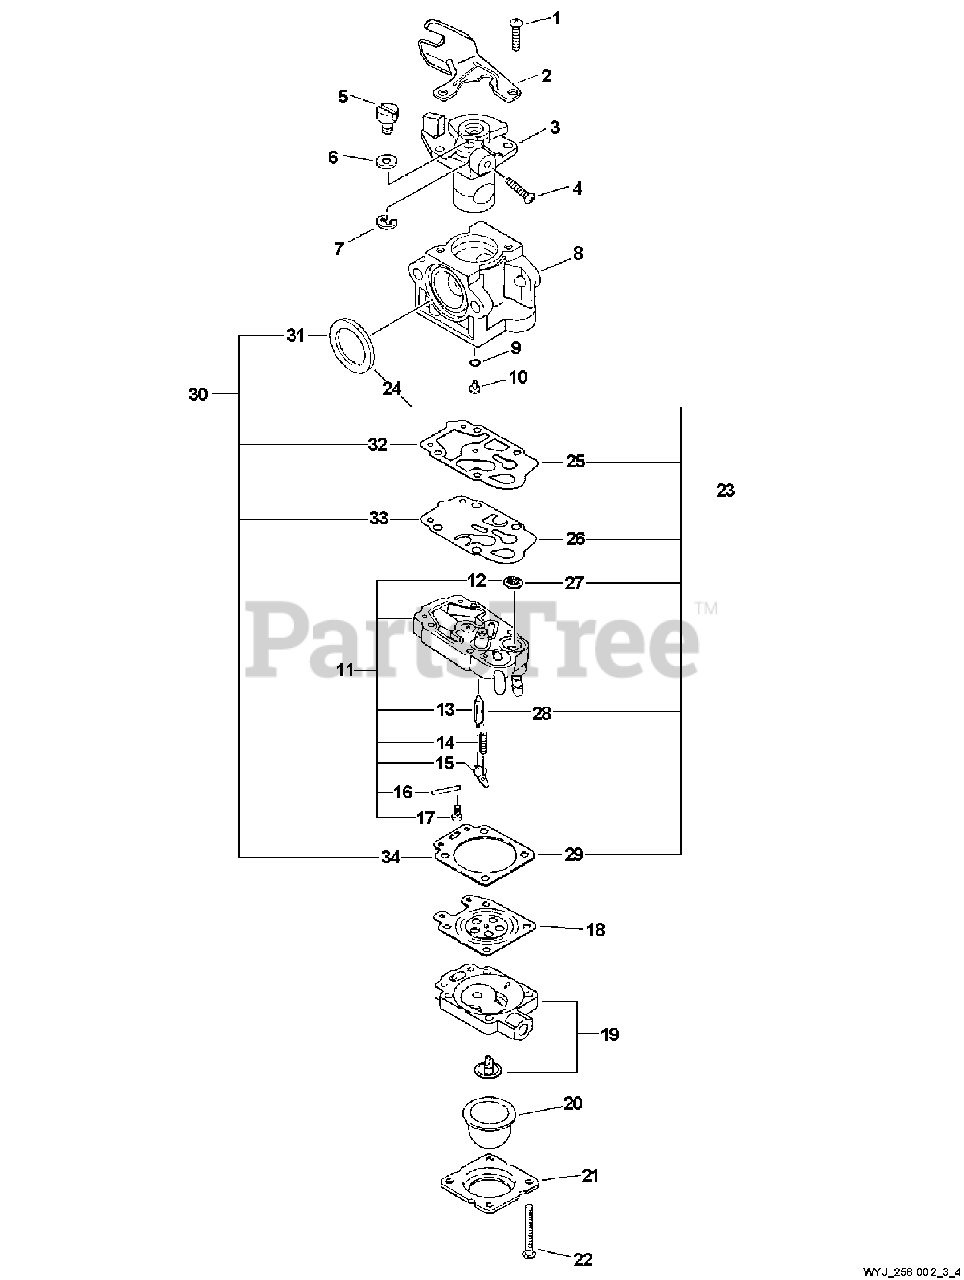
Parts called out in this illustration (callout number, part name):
2	BRACKET, CABLE
3	THROTTLE VALVE ASSY
4	SCREW, IDLE ADJUST
7	RING, RETAINING
8	BODY, CARBURETOR
11	PUMP BODY ASSY
12	STRAINER
13	VALVE, INLET NEEDLE
14	SPRING, METERING LEVER
15	LEVER, METERING
16	PIN, METERING LEVER
17	SCREW, METERING LEVER PIN
18	DIAPHRAGM, METERING
19	PURGE BASE ASSY
20	BULB, PURGE
21	RETAINER, PURGE BULB
22	SCREW, PUMP COVER
23	REPAIR KIT
24	SEAL
25	GASKET, PUMP
26	DIAPHRAGM, PUMP
27	STRAINER
28	VALVE, INLET NEEDLE
29	GASKET, DIAPHRAGM
30	DIAPHRAGM/GASKET KIT
31	SEAL
32	GASKET, PUMP
33	DIAPHRAGM, PUMP
34	GASKET, DIAPHRAGM
